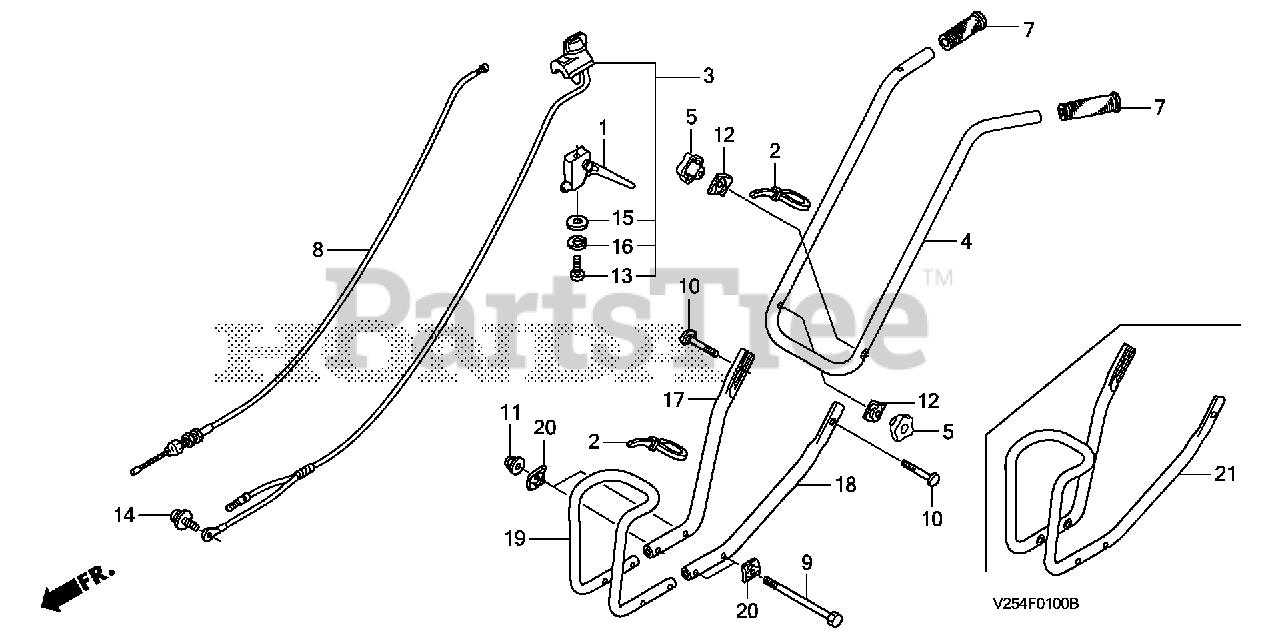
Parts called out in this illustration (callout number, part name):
1	LEVER ASSY., THROTTLE
2	TIE, CABLE (157.5MM)
3	SWITCH ASSY., ENGINE STOP
4	PIPE, HANDLE (UPPER)
5	GRIP, HANDLE JOINT
7	GRIP, HANDLE
8	CABLE, CLUTCH
9	BOLT, HEX. (6X160)
10	BOLT, HANDLE HOLDER
11	NUT, NYLON LOCK (6MM)
12	WASHER, FRAME JOINT
13	SCREW, PAN (3X12)
14	SCREW-WASHER (5X12)
15	WASHER, PLAIN (3MM)
16	WASHER, SPRING (3MM)
17	PIPE, R. HANDLE (LOWER)
18	PIPE, L. HANDLE (LOWER)
19	HANDLE, CARRY
20	WASHER, FRAME JOINT
